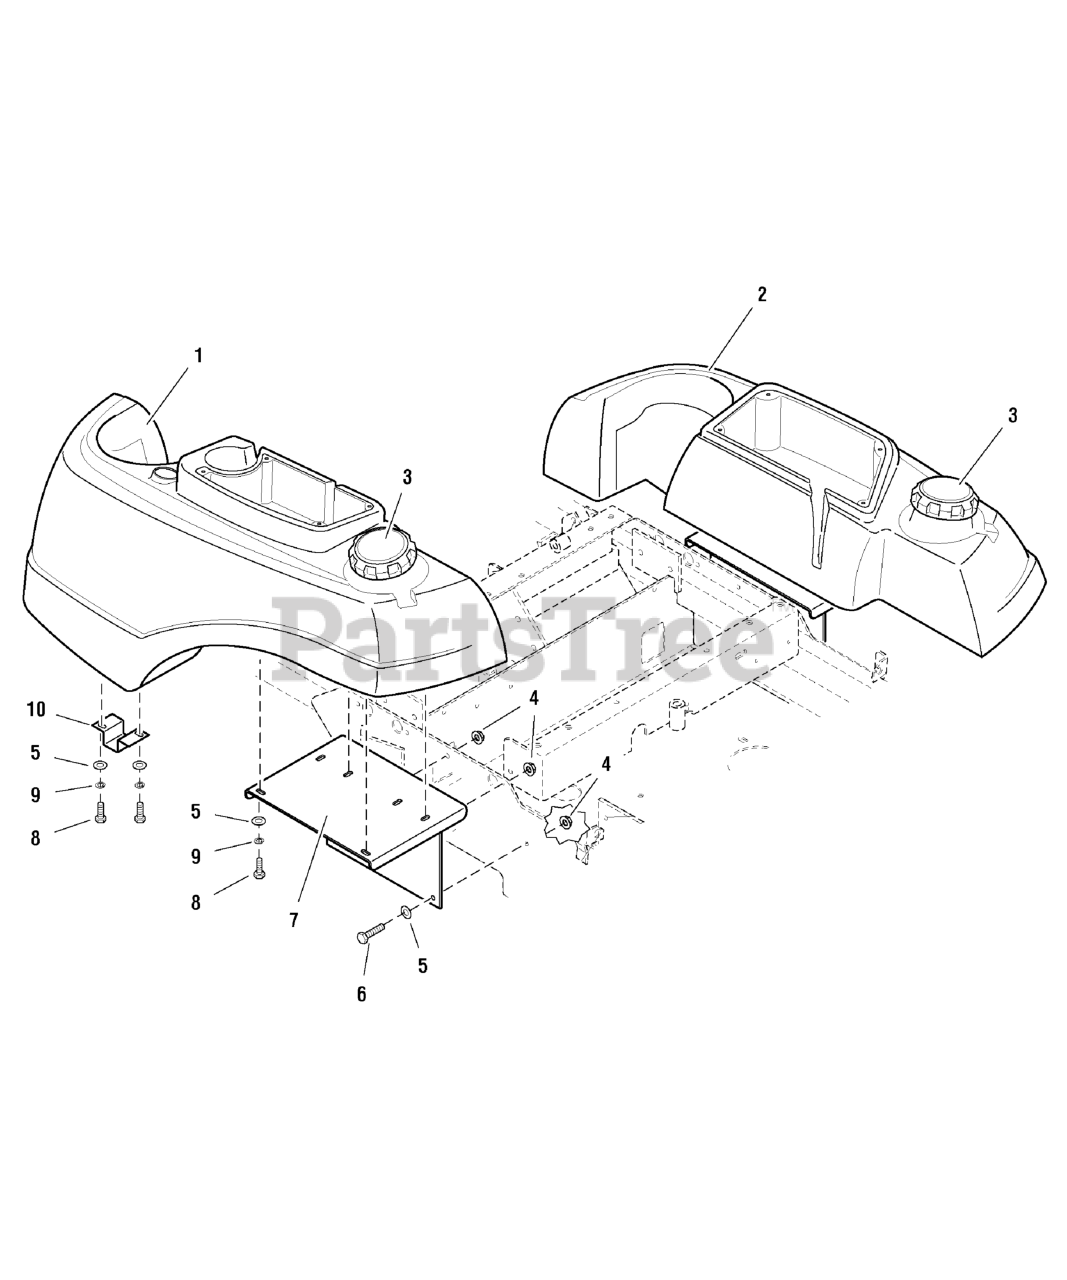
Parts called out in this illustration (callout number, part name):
1	FUEL TANK, IS5000Z, LH
2	FUEL TANK, IS5000Z, RH
3	FUEL TANK CAP, DIESEL
4	NUT, 5/16-18 HEX SERRATED FLANGE (LARGE)
5	WASHER, 5/16" SAE
6	BOLT, 5/16-18 X 1 GD5 YZ
7	FUEL TANK MOUNT
8	BOLT, 5/16-18 X 3/4 GD5
9	WASHER, 5/16 LOCK CZ
10	GUARD, Tank Valve
